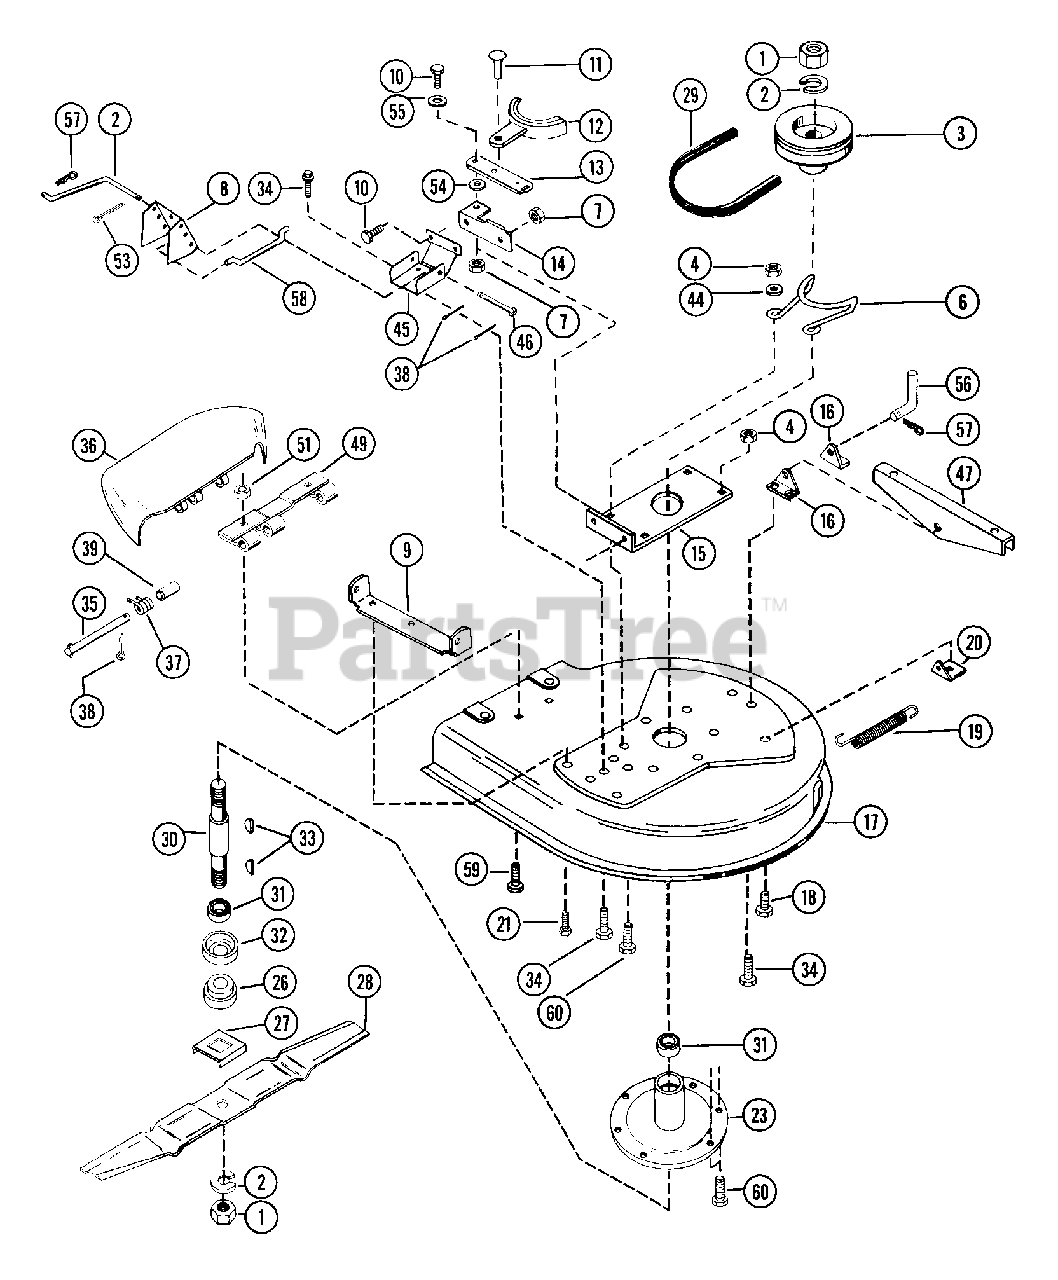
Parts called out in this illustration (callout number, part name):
1	NUT-JAM .75-10 PL
2	WSHR-LK .750X.188 MED PL
3	MOWER SHEAVE
4	NUT-LK-CTR .375-16 GR A PL
6	BELT FINGER
7	NUT-LK .312-18 GR A PL
8	MOWER ENGAGING ARM
9	FRONT MTG BRACKET
10	BLT-HEX .31-18X.63 PL GR 2
11	RVT .25X.50 RH ST
12	BLADE BRAKE
13	MOWER BRAKE LEVER
14	BRAKE BRACKET
16	REAR MTG BRACKET
17	26 IN MOWER PAN W/ DECALS
18	BLT-SERHFWH .25-20X.50 PL
19	SG-TENS .072X.51X5.31 WLD 25
20	BRAKE CLIP
21	BLT-SCRHFWH .38-16X.50 PL
23	SPINDLE HOUSING
26	RETAINER HUB
27	BLADE TRAY
28	MOWER BLADE 26
29	V-BELT, 4L-WRAPPED
30	SPINDLE SHAFT
31	BRG-BALL .750X1.781X.61
32	BEARING SLINGER
33	KEY-WDRF .188X.75X.313 SAE 9
34	BLT-SERHFWH .31-18X.50 PL
35	CLEVIS PIN
36	PAN CHUTE EXTENSION
37	SG-TORS .095X.50X 1.0
38	PIN-COTR .09X.75 PL
39	BSHG-SLV .334 X .502 X 1.437
44	WSHR-FL-STL .406X.865X.094 PL
45	PIVOT BRACKET
46	PIN-CLEV .309X3.50 SP
47	SWIVEL BRACKET
49	HINGE PLATE
51	NUT-LK-CTR .250-20 PL
52	MOWER ENGAGEMENT LINK
53	PIN-COTR .12X.75 PL
54	SPACER BUSHING .5 X .32 X .163
55	WSHR-FL-STL .328X1.0X.094
56	CLEVIS PIN
57	PIN-HAIR INT .08X.38X1.42 YWZC
58	MOWER BRAKE LINK
59	BLT-RDHDSQNK .25-20X.50 SHT PL
60	BLT-HEX .38-16X1.00 PL
